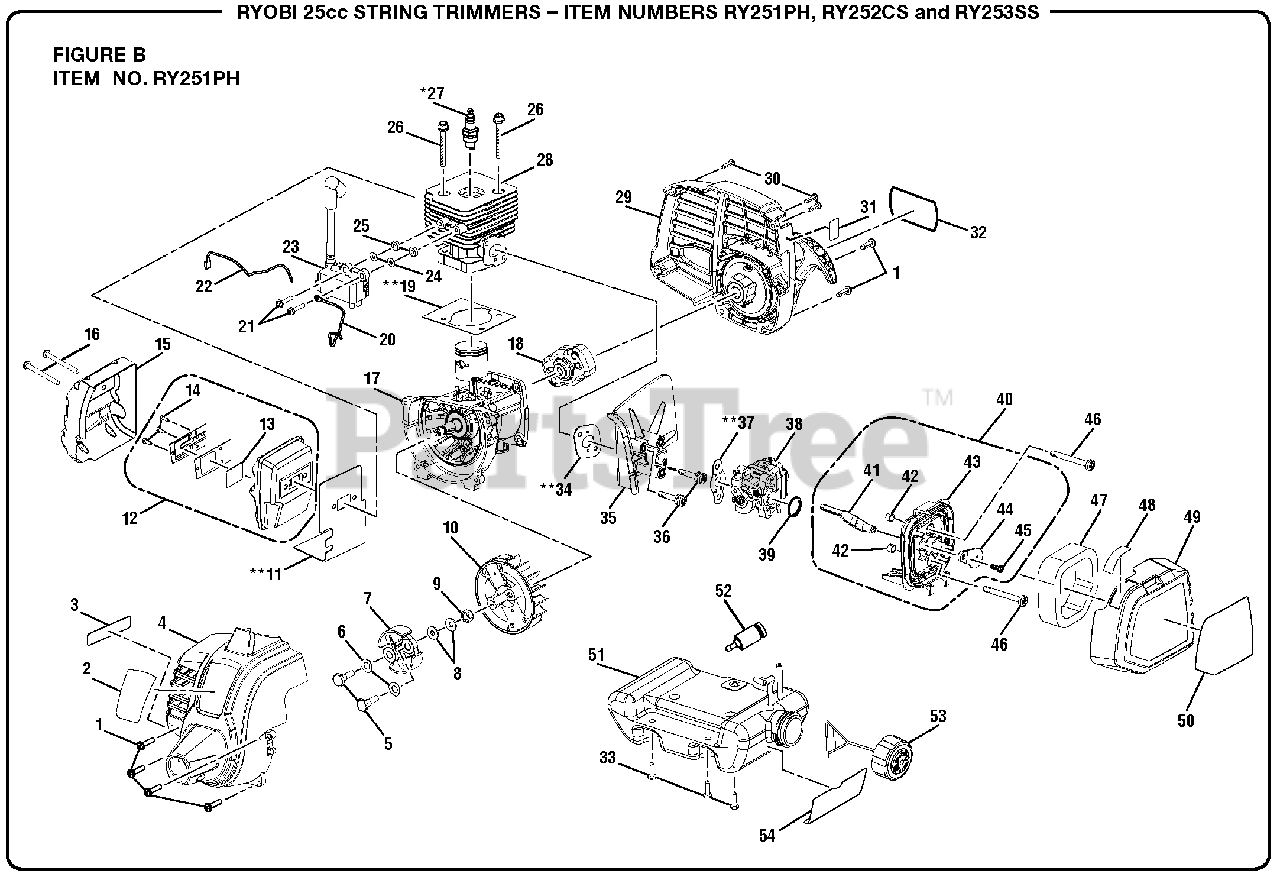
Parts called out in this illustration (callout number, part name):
1	Screw w/Washer (M5 x 20 mm, T20 Torx Pan Hd.)
2	Logo Label (Front)
3	Combustion Warning Label
4	Front Housing Assembly
5	Clutch Shoulder Bolt (M6 x 22.5 mm, Hex Hd.)
6	Curved Washer
7	Clutch Assembly
8	Washer (ID6 x OD15 x 1.2t)
9	Flywheel Nut
11	Muffler Gasket
12	Muffler Assembly
13	Screen
14	Screw (6-20 x 1/4 in., T20 Torx Pan Hd. S.T.)
15	Heat Shield
16	Screw (M5 x 50 mm, T25 Torx Pan Hd.)
17	Crankcase Assembly
18	Starter Cup
19	Gasket
20	Lead Wire (Red)
21	Screw w/Washer (M4 x 22 mm, T20 Torx Pan Hd. S.T.)
22	Lead Wire (Black)
23	Coil Boot Assembly
24	Washer (ID4.2 x OD10 x 1t)
25	Spacer (Phenolic)
26	Screw (M5 x 22 mm, Soc. Hd.)
27	Spark Plug (Torch L7RTC)
29	Screw (M4 x 18 mm, T20 Torx Pan Hd. S.T.)
30	Primer Bulb Location Label
31	Logo Label (Rear)
32	Shoulder Screw (M4 x 14 mm, T25 Torx Truss Hd.
33	Insulator Gasket
34	Heat Dam Insulator
35	Screw (M5 x 30 mm, T25 Torx Pan Hd. S.T.)
37	Carburetor Assembly
38	Carburetor O-Ring
39	Airbox Base Assembly
40	Choke Lever
41	Compression Limiters
42	Air Box Base
43	Choke Plate
44	Screw (M4 x 12 mm, T20 Torx Pan Hd. S.T.)
45	Screw (M5 x 44 mm, T20 Torx Pan Hd.)
46	Air Filter
47	Choke Position Label
48	Airbox Cover
49	Starting Instructions Label
50	Fuel Tank and Cap Assembly
51	Fuel Tank and Cap Assembly
52	Fuel Filter
53	Fuel Cap Assembly
54	Fuel Mixture Label
